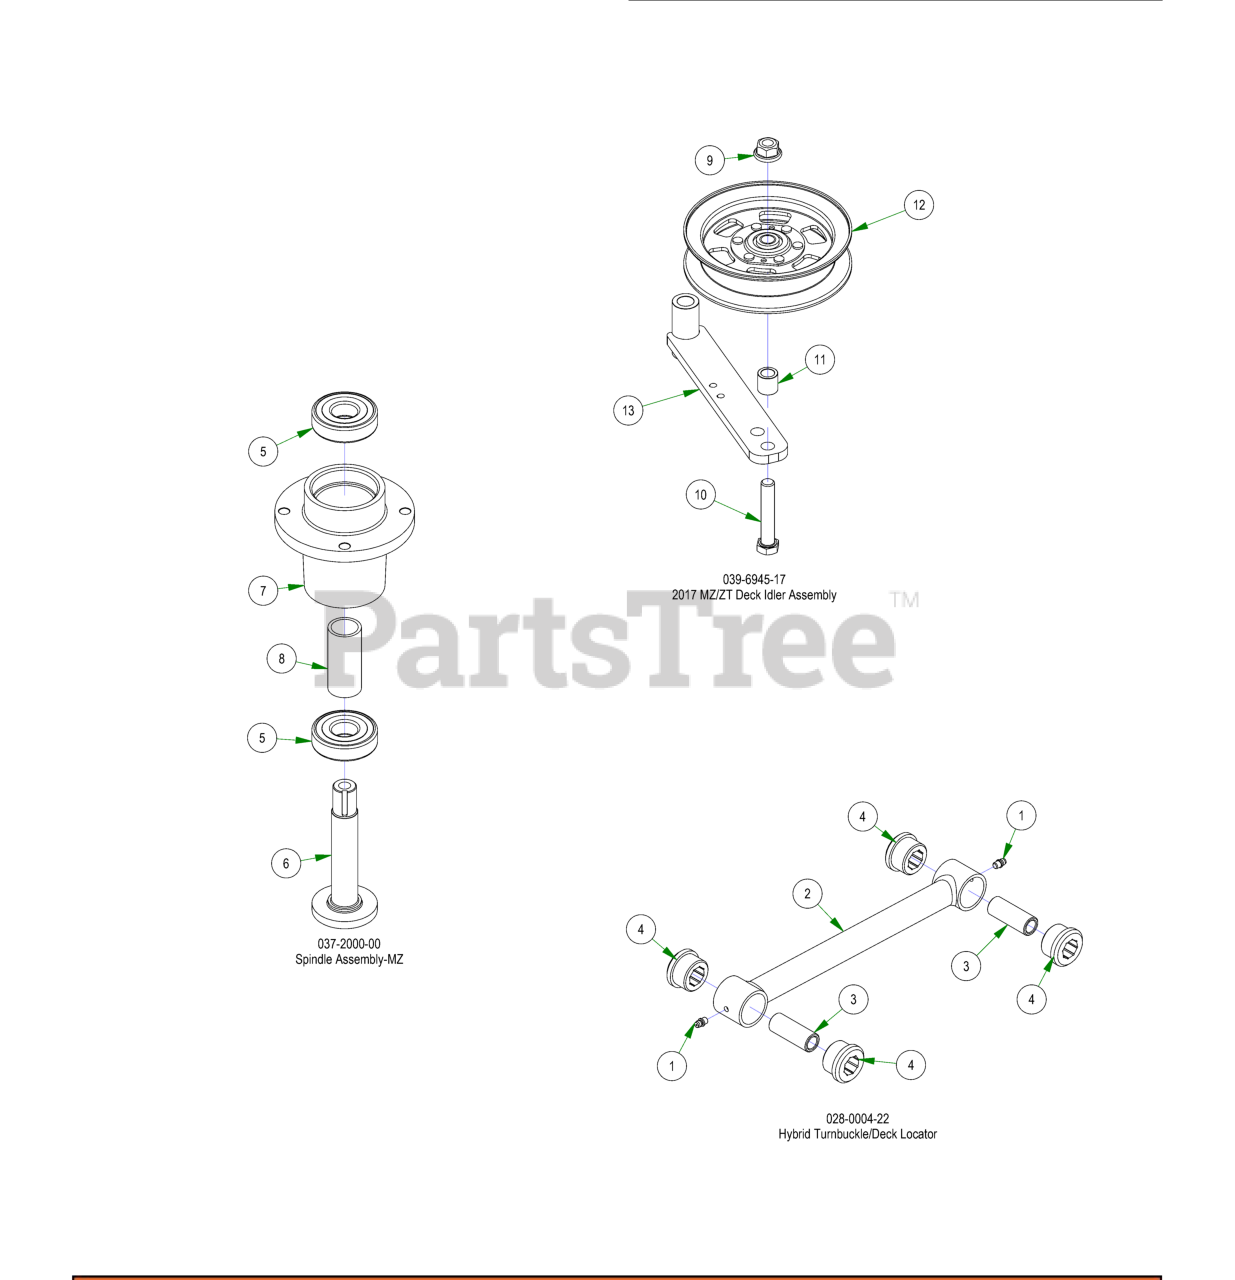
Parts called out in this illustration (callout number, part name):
1	1/4-28 Grease Fitting
2	2022 Isolator Turnbuckle Body
3	2018 Maverick Bushing Sleeve
4	2018 Maverick Bushing
5	Spindle Bearing
6	Spindle Shaft
7	Spindle Housing
8	Spindle Spacer-Component
9	1/2-13 NYLON INSERT FLANGE LOCKNUT ZINC
10	1/2-13 X 2-3/4 HEX CAP SCREW (GR.5) ZINC
11	Spacer 3/4 OD x 1/2 ID x 3\4 Length
12	5" Idler Pully
13	Deck Idler
